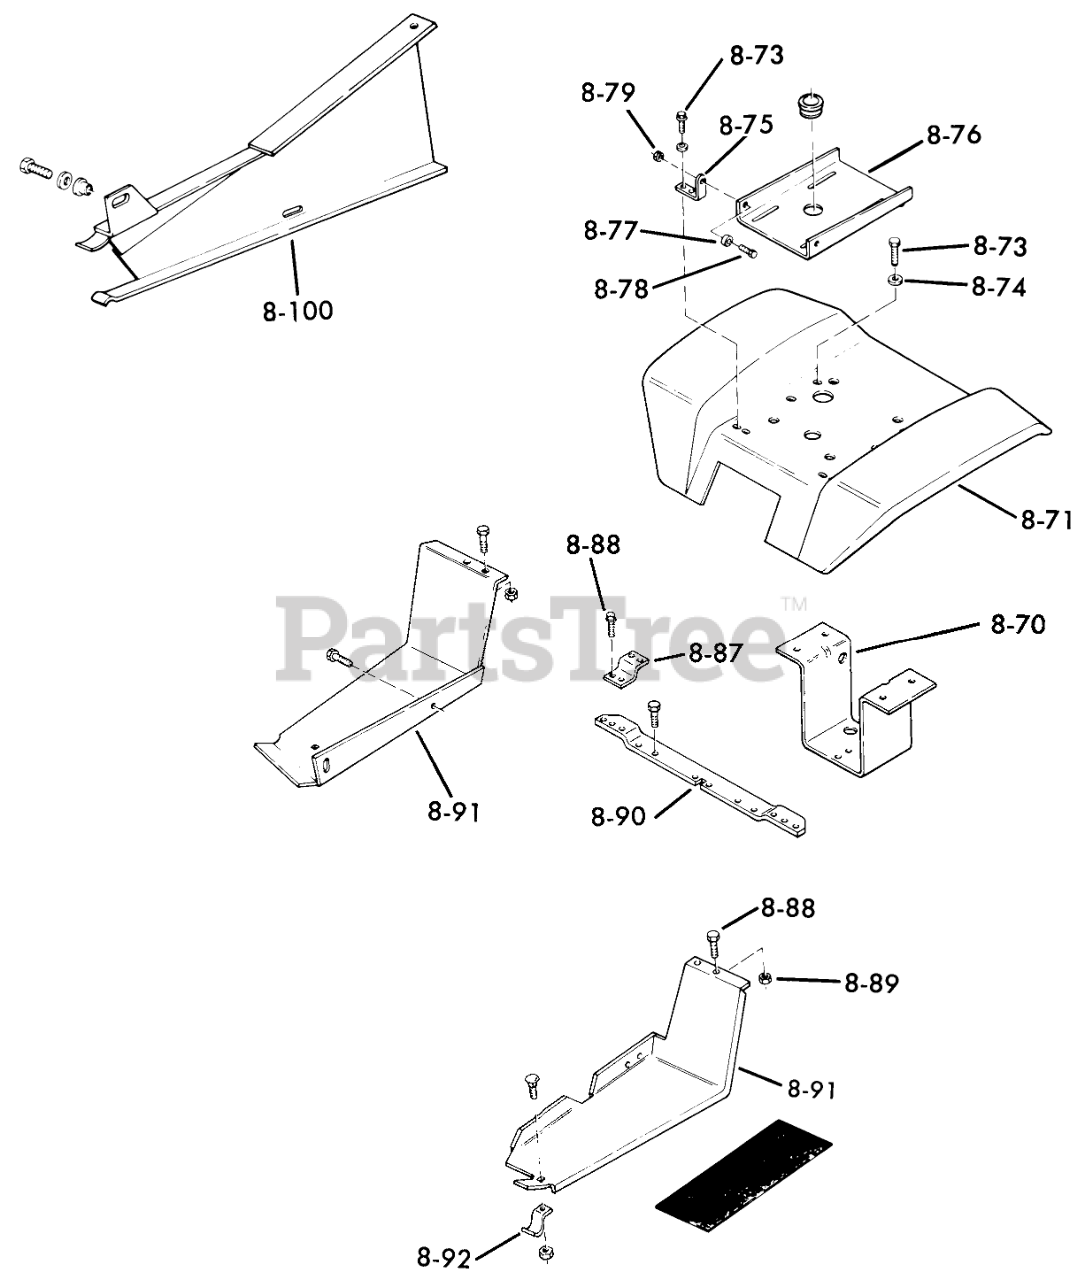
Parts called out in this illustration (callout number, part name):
8-06A	ROD-HOOD STOP
8-06A	Cotter Pin
8-44	Tape
8-70	Bracket-Fender
8-71	Fender
8-73	Bolt
8-74	WASHER 5/16 SAE
8-75	BRACKET-PIVOT
8-76	Plate Seat Pivot
8-77	BUSHING
8-78	HHCS
8-79	Nut
8-87	BRACKET-FENDER R
8-88	HHCS
8-88	Nut
8-88	BUMPER-RUBBER
8-90	Bracket-Footrest
8-90	SCREW
8-91	Footrest-RH
8-91	Footrest-LH
8-91	PAD-FOOTREST
8-91	Bolt
8-91	Nut
8-91	Screw
8-92	BRACKET
8-92	Bolt
8-92	Nut
8-100	Belt Guard Assy
8-100	H H C S
8-100	LOCKWASHER
8-100	Bolt
8-100	Screw
